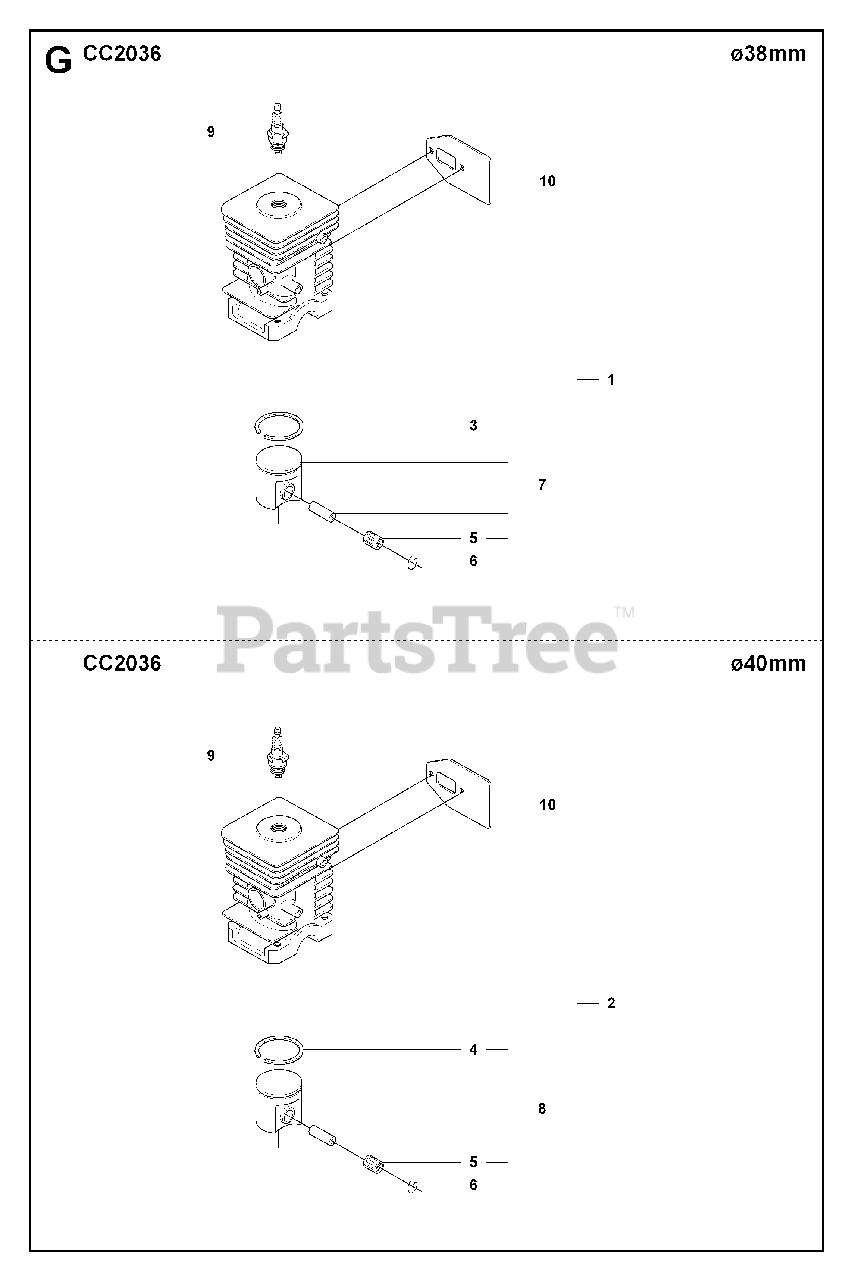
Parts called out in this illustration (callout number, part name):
1	CYLINDER W/PISTON
3	PISTON RING 36
4	PISTON RING
5	SUPPORT BUSHING
6	LOCKING RING
7	PISTON COMPLETE
8	PISTON ASSY
9	SPARK PLUG RCJ7Y
10	GASKET MUFFLER
